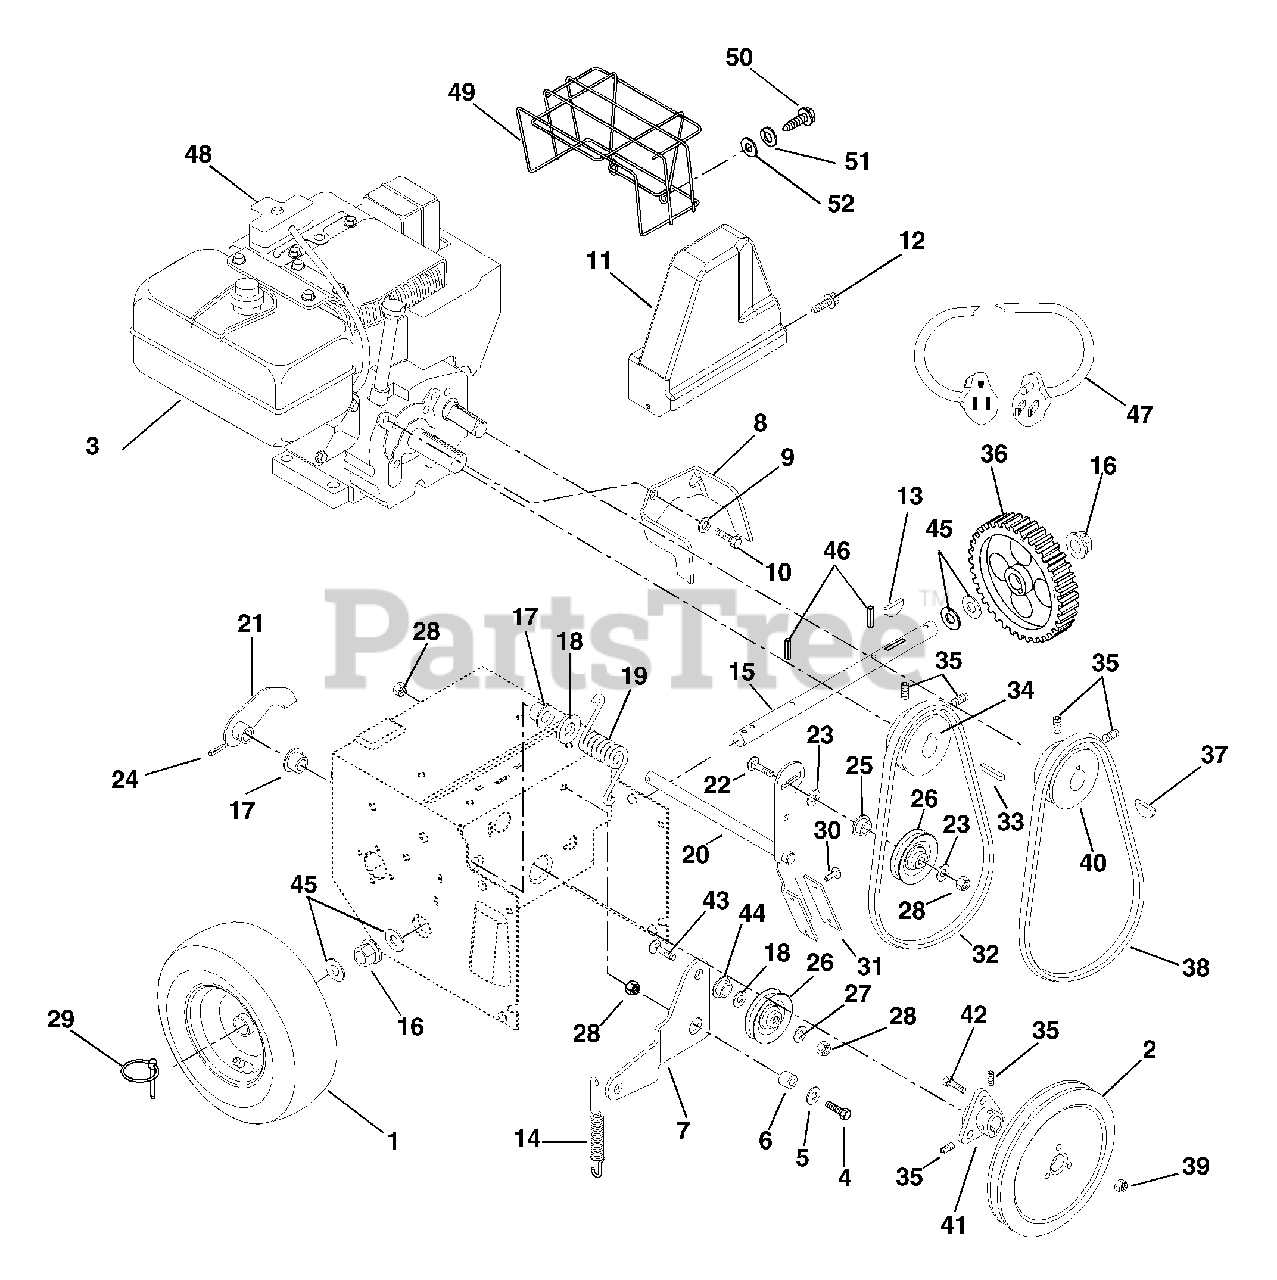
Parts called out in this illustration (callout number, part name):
1	WHEEL 5.00 X 6.00
1	TIRE 15 X 5.00-6 2P SNOWHOG
1	TIRE/WHEEL ASSY, 15 X 5.00-6
2	PLY-V 8.0 X 1.25 3BLT SALEM
3	ENGINE, 8HP LH TEC. - 120V
3	ENGINE, 8HP LH TEC. - 220V
4	@BLT-HEX .31-18X.75 GR5 YWZC
5	@WSHR-FL-STL.38X.875X.083 YWZC
6	SPACER BUSHING .5 X .32 X .163
7	IDLER ARM
8	FINGER, BELT
9	@WSHR-LK .31X.078 REG YWZC
10	BLT-HEX .31-24X.75 YWZC GR5
11	COVER, BELT
12	@SCR-TAP .25-20X.37 HWH YWZ TR
13	KEY-WDRF .25X.750X.313 SAE91
14	SG-TENS .047X.44X3.37 WLD 1.47
15	SHAFT, AXLE
16	BSHG-FLG .750X.873HEXX.53X1.18
17	BSHG-FLG.500X.625X.312X.750NY
18	WSHR-FL-STL .520X.810X.033YWZC
19	SG-TORS .148X1.0X1.53
20	CLUTCH ARM W/BRAKE PAD
21	ARM-CLUTCH
22	@BLT-RDHDSQNK .31-18X1.50 G5YZ
23	@WSHR-FL-STL.38X.875X.083 YWZC
24	PIN-ROLL .156X.88
25	SPCR, BRG .315X.50X.688X.281
26	IDLER
27	@WSHR-FL-STL.38X.875X.083 YWZC
28	@NUT-LK-CTR .31-18 YWZC
29	PIN-LOK .31X1.75
30	RVT-TBLR .187X.437 RH ST PL
31	BRAKE LINING
32	V-BELT, 4L-RAW EDGE
33	KEY-STR .25X1.75X.25
34	SHEAVE, ENGINE-BLOWER
35	SCR-SET .31-18X.38 SKHCUPDL
36	SPUR GEAR, FELLOWS 35T .750 ID
37	KEY-WDRF .125X.625X.250 SAE5
38	V-BELT, 3L-RAW EDGE
39	@NUT-SPNLK-FLG .312-18 YWZC
40	PULLEY-CAMSHAFT
42	BLT-SERRDHD SL .31-18X.75 YZ
43	@BLT-RDHDSQNK .31-18X1.25 G5YZ
44	BSHG, FLG .325X.499X.26X.88
45	WSHR-FL-STL.754X1.125X.062YWZC
46	PIN-ROLL .188X1.25
47	CORD, ELECTRIC START CORD 120V
48	120 V STARTER KIT- 8 TO 11.5HP
48	240V. ELECTRIC START
49	MUFFLER GUARD 8 & 10 HP
50	SCR-TAP 10-16X.75 YWZC
51	@WSHR-LK #10X.047 REG YWZC
52	@WSHR-FL-STL.219X.50X.049 YWZC
